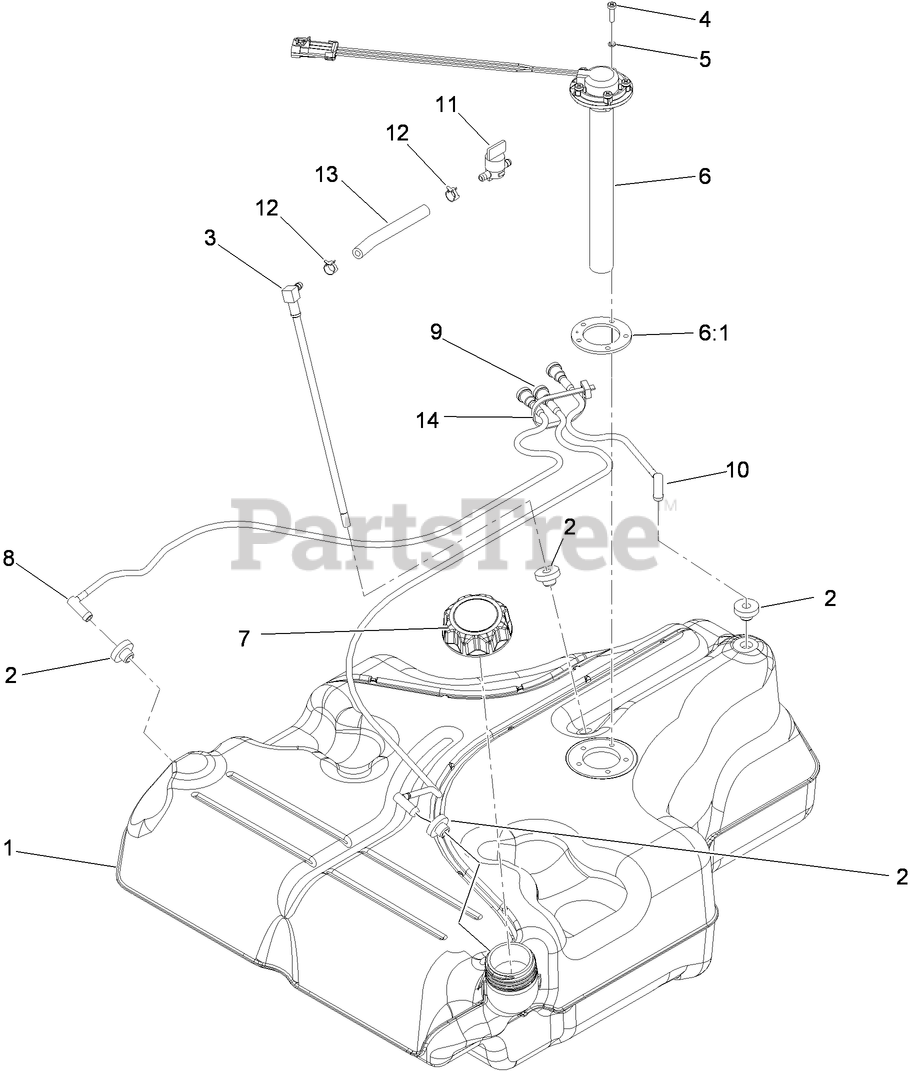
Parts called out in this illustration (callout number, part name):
1	TANK-FUEL, BELLY
2	BUSHING
3	FUEL LINE KIT (WITH GROMMET)
4	SCREW-PAN
5	WASHER-LOCK
6	SENDER-LEVEL, FUEL
6:1	GASKET-SENDER, FUEL
7	CAP-FUEL
8	RH VENT LINE KIT (WITH GROMMET)
9	LH VENT LINE KIT (WITH GROMMET)
10	REAR VENT LINE KIT (WITH GROMMET)
11	VALVE-FUEL
12	CLAMP-HOSE
13	HOSE-FUEL
14	TIE-PLASTIC
